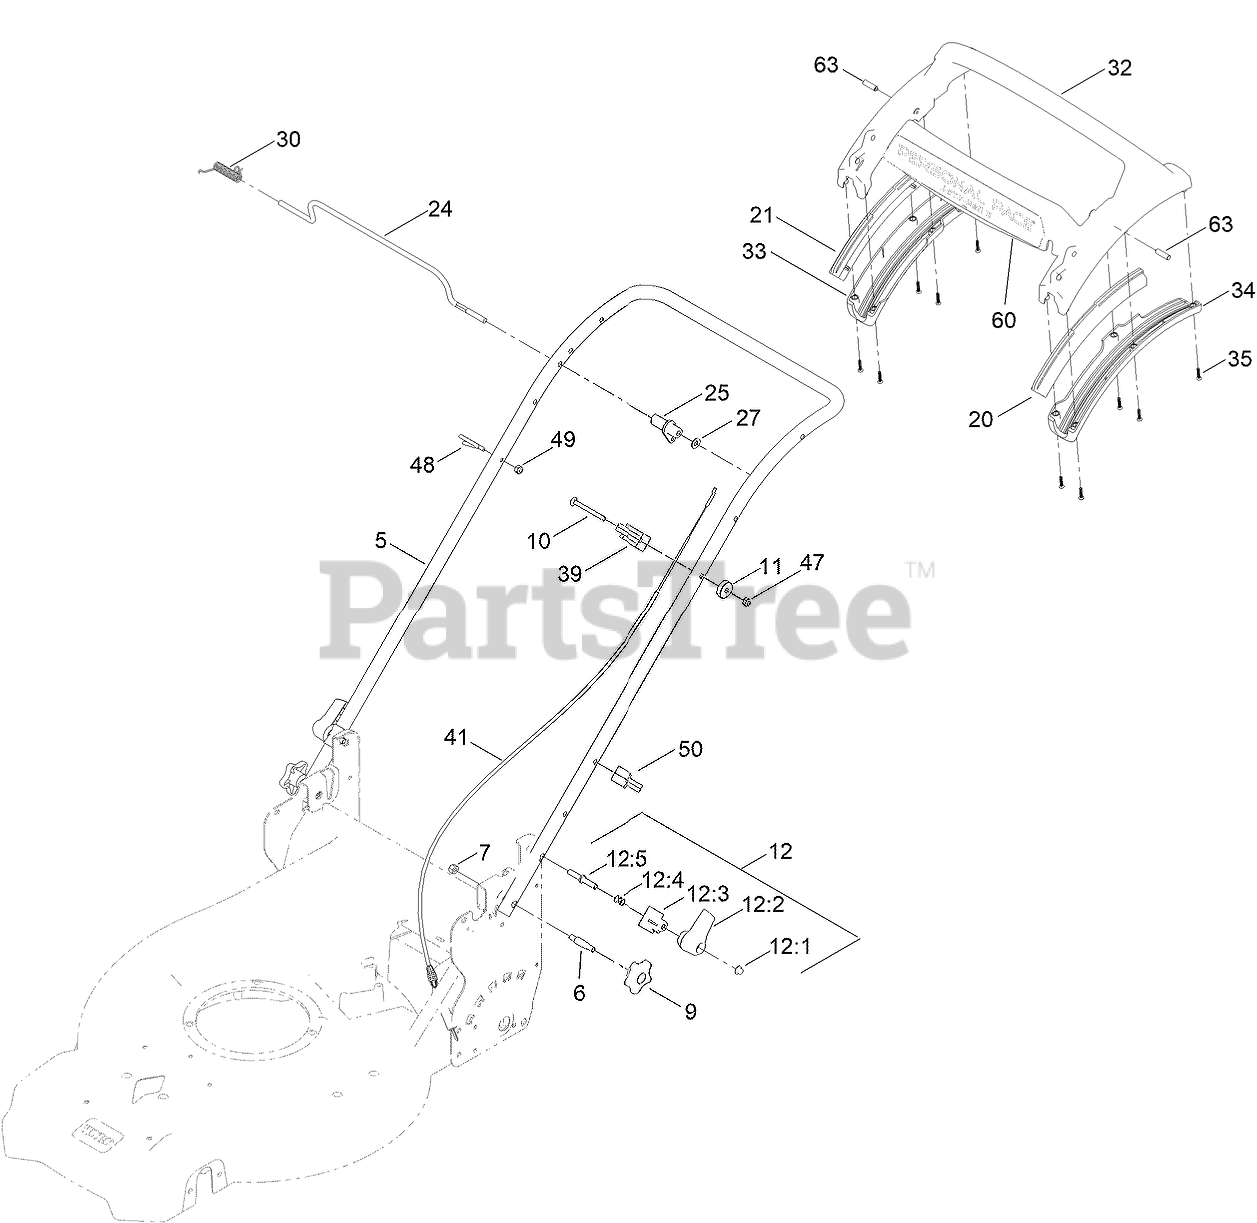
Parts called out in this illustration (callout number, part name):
5	HANDLE-CURVED
6	BOLT-SHOULDER, HANDLE
7	NUT-LOCK, NI
9	KNOB-HANDLE
10	SCREW-CARR
11	WASHER-CURVED
12	QUICK RELEASE ASM
12:1	NUT-PUSH
12:2	LEVER-RELEASE
12:3	ANCHOR-SPRING
12:4	SPRING-COMPRESSION
12:5	ROD-RELEASE
20	GUIDE-CURVED, LH (RWD)
21	GUIDE-CURVED, RH (RWD)
24	ROD-CONTROL, TRACTION
25	LEVER-TRACTION, RWD
27	WASHER-PLAIN
30	SPRING-TORSION
32	HANDLE-PERSONAL PACE, CURVED
33	BOTTOM-HANDLE, RH
34	BOTTOM-HANDLE, LH
35	SCREW-PPH
39	ANCHOR-CABLE, RWD
41	CABLE-TRACTION, RWD (PP)
47	NUT-LOCK, NI
48	GUIDE-ROPE
49	NUT-HEX
50	GUIDE-CABLE
60	DECAL-HANDLE, PP
63	PIN-HANDLE, PP
